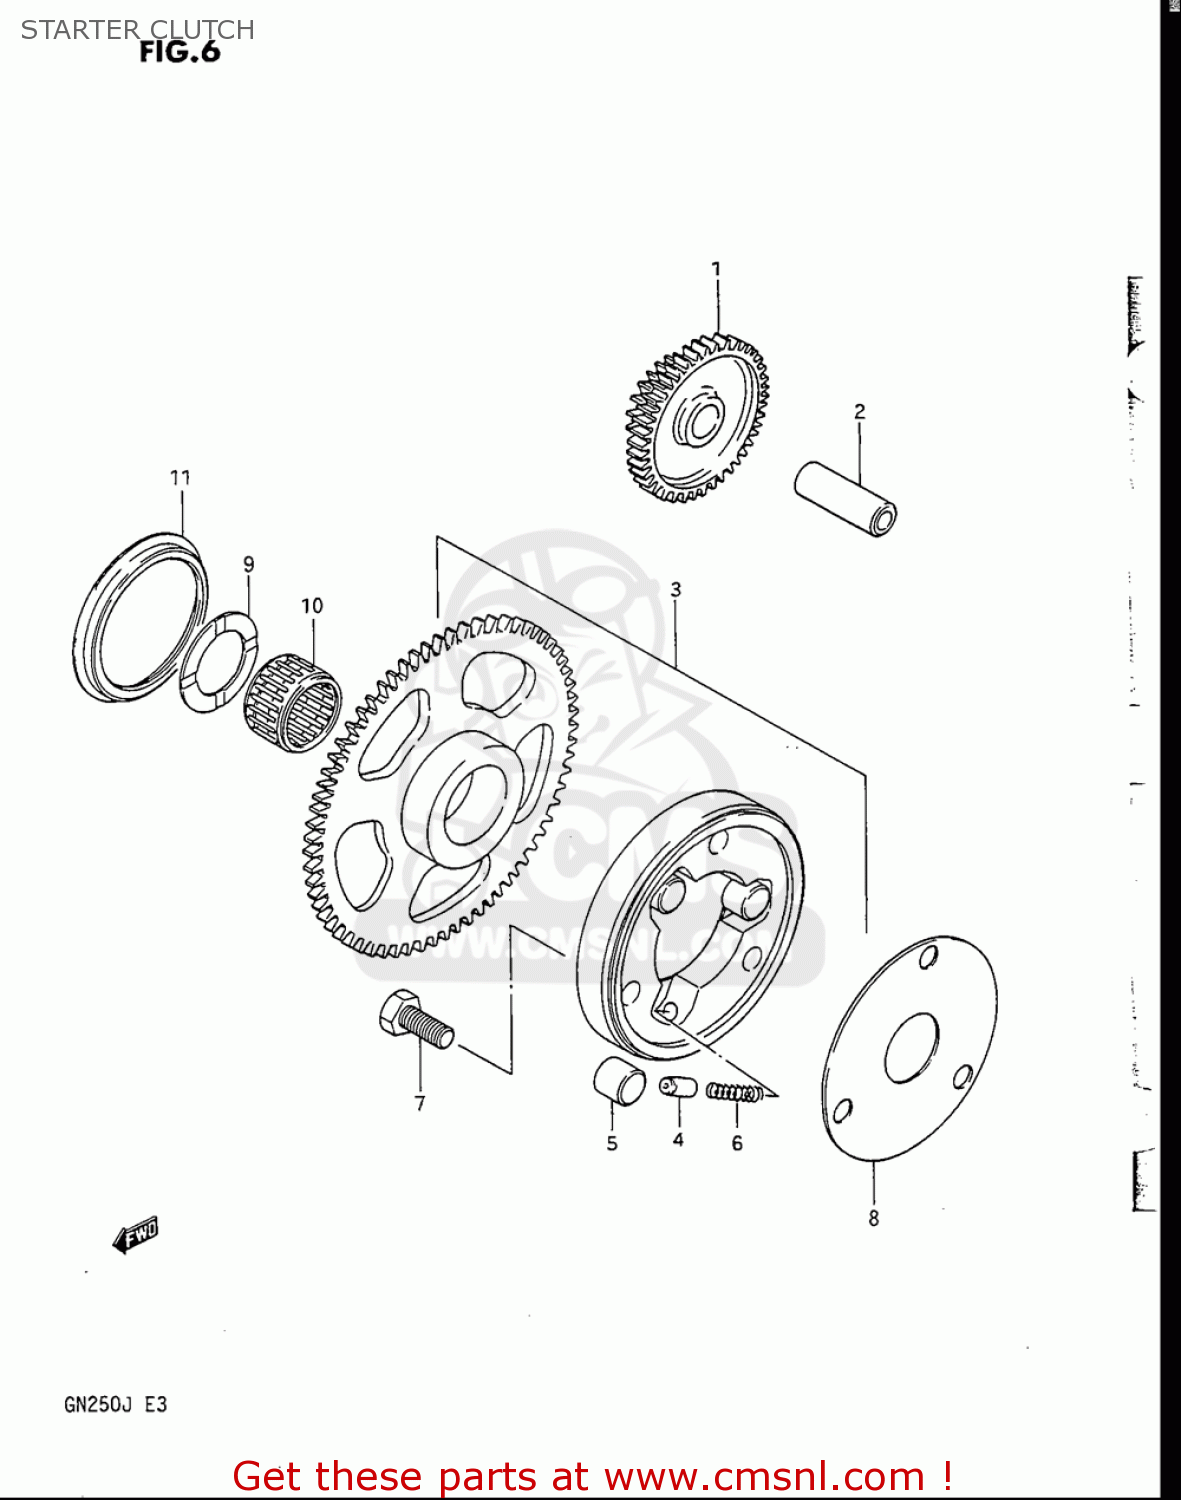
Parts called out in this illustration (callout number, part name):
1	GEAR,STARTER IDLE
2	PIN(7.4X13X40)
3	CLUTCH SET,STA
4	PIECE,PUSH
5	PIN(14X13)
6	SPRING
7	BOLT
8	SHIM,STARTER CLUTCH HUB
9	WASHER(27X40X2.5)
10	BEARING(27X32X21.8)
11	SEAL,OIL(52X62X6.8)
